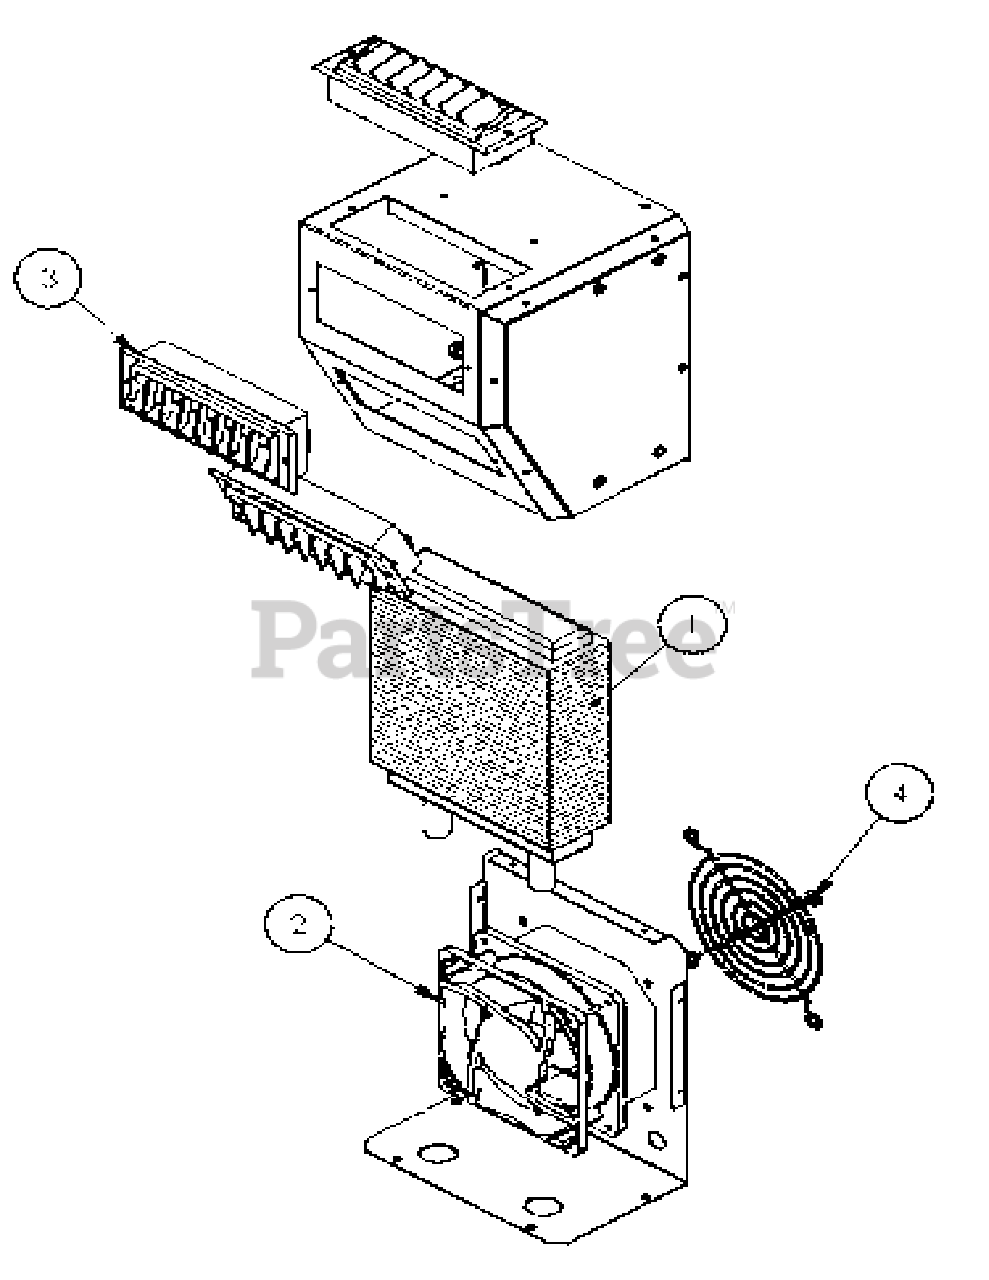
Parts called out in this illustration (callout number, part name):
1	Heater Core - 20,000 BTU
2	Fan/Motor - 20,000 BTU
3	Vent/Louver Rectangle
4	Fan Guard - 20,000 BTU
